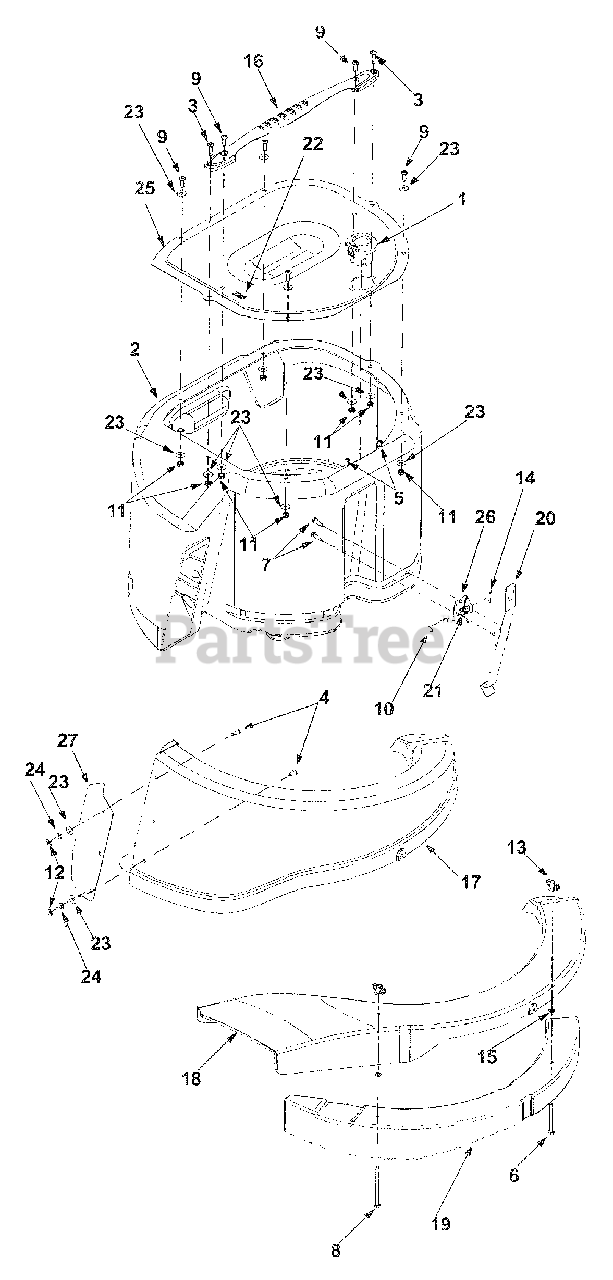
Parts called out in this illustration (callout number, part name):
1	Flow Indicator Assembly
2	Grass Bag Assembly
3	Machine Screw 1/4-20 x 1.0
4	Machine Screw 1/4-20 x 0.5"
5	Hex Screw #10-16 x 0.5"
6	Hex Screw 1/4-20 x 2.75"
7	Self-Tapping Screw 1/4-20 x 0.75"
8	Hex Screw 1/4-20 x 3.75"
9	Machine Screw 1/4-20 x 0.75"
10	Clevis Pin
11	Hex Sems Nut 1/4-20
12	Jam Nut
13	Wing Nut
14	Cotter Pin
15	Speed Nut
16	Bag Handle
17	Discharge Chute: Grass Bag
18	Side-Discharge Chute
19	Mulching Plug
20	Bag Release Lever
21	Torsion Spring
22	Clip Spring
23	Flat Washer
24	Lock Washer
